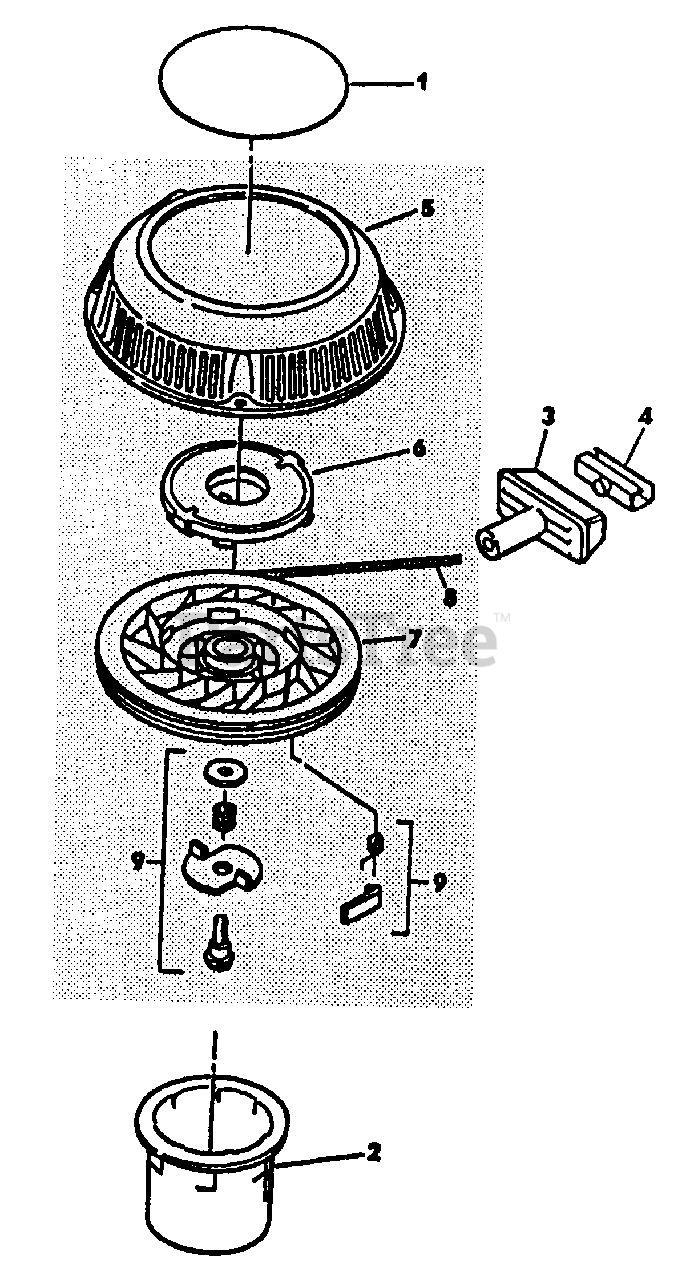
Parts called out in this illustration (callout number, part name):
1	Decal
2	Starter Hub
3	Starter Handle
4	Rope Clip-Starter Insert
5	Starter Housing and Shaft
6	Recoil Spring and Keeper
7	Pulley
8	Rope
9	Dog Kit
